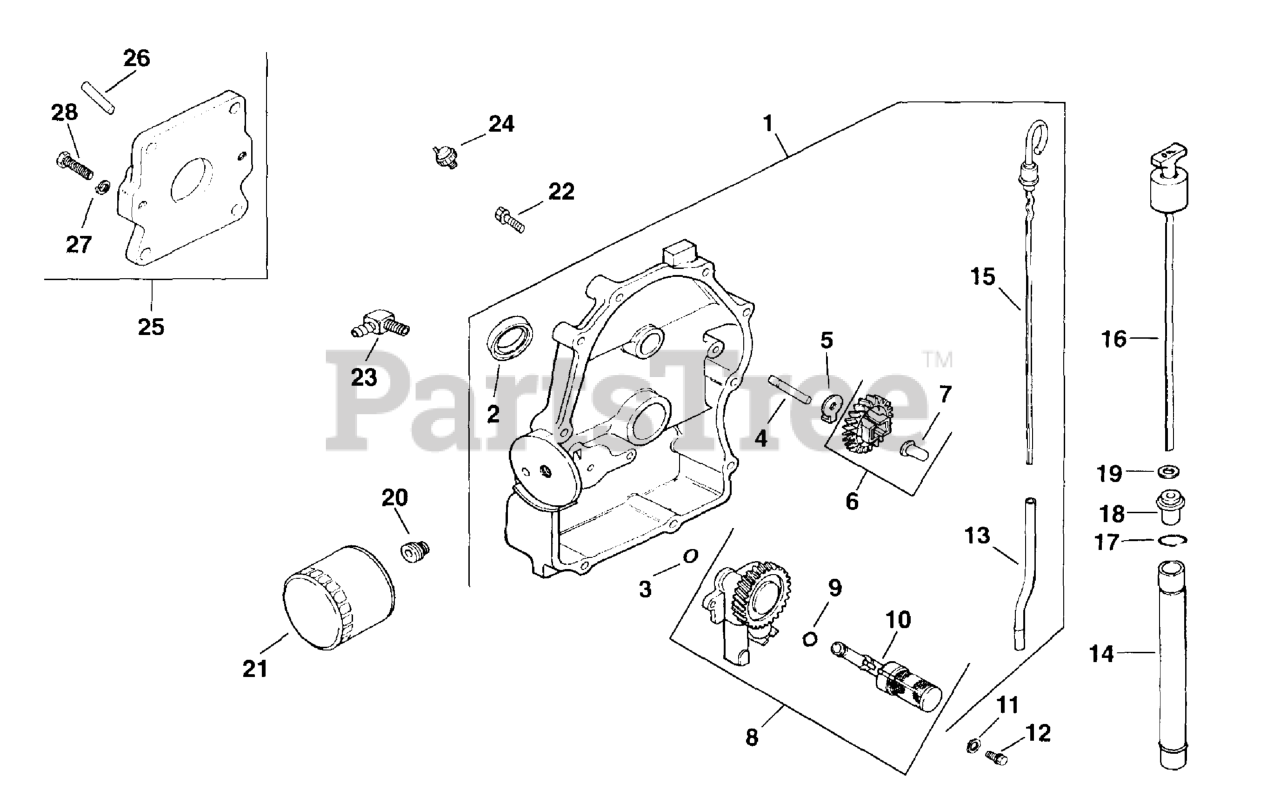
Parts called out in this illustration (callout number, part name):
2	SEAL, OIL (KM)-USE 25 032 06-S
4	SHAFT, GOVERNOR GEAR
6	KIT, GOVERNOR GEAR W/PIN
7	PIN, GOVERNOR REGULATING
8	PUMP, OIL - DISCONTINUED
9	O-RING, OIL PICK-UP
10	PICK-UP, OIL - DISCONTINUED
10	PICK-UP, OIL
11	WASHER - USE M-631005
12	SCREW - USE M-645025
20	NIPPLE, OIL FILTER USE 24 136 09-S
21	OIL FILTER
22	SCREW, HEX FLANGE -USE 24 086 17-S
23	CONNECTOR, 90 DEG. HOSE
24	SWITCH - USE 25 099 24
